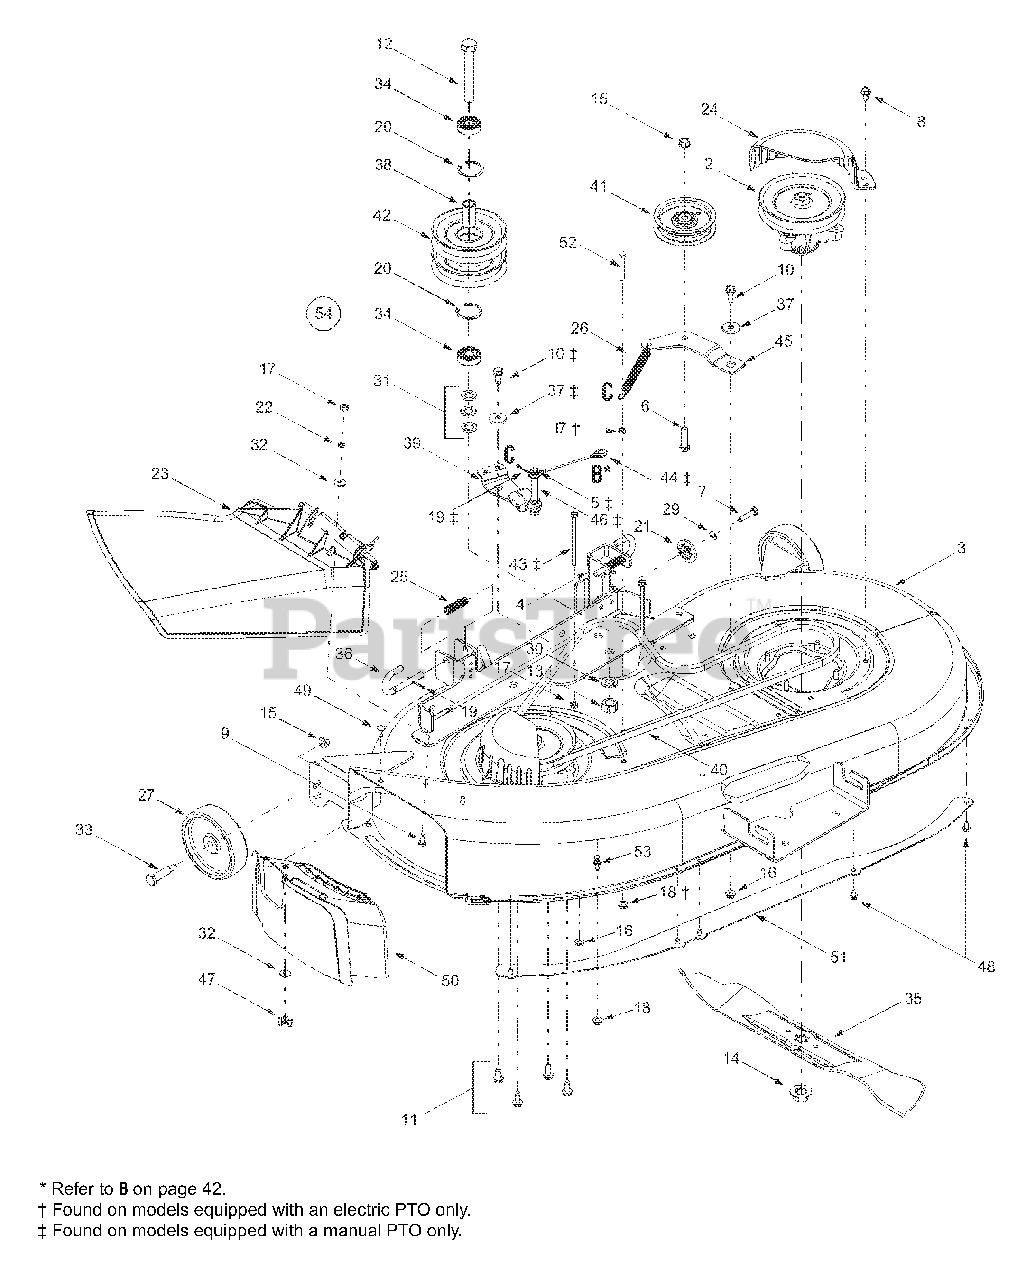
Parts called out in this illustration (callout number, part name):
2	Spindle Assembly, 5.75 Dia.
5	Flat Washer, .385 x .62 x .063
6	Hex Cap Screw, 1/4-20 x 1.5
7	Hex Cap Screw, 5/16-18 x 1.25
8	Self-tapping Screw, 5/16-18 x .75
9	Hex Cap Screw, 1/4-20 x .62
10	Hex Head Washer Screw, 5/16-18 x .875
11	Self-tapping Screw, 5/16-18 x .88
12	Hex Cap Screw, 5/8-18 x .875
13	Hex Nut, 5/8-18
14	Hex Flange Nut, 5/8-18
15	Flange Lock Nut, 3/8-16
16	Flange Lock Nut, 5/16-18
17	Hex Nut, 1/4-20
18	Hex Flange Lock Nut, 1/4-20
19	Cotter Pin, 1/8 x 1.25
20	Internal Snap Ring
21	Deck Adjustment Gear
22	Push Nut. .25 x .5
23	Side Discharge Chute Assembly
24	Belt Cover
25	Compression Spring, .406 x .531 x 1.75
26	Extension Spring, .50 x 4.74
27	Deck Wheel, 5 x 1.38
29	Lock Washer, 5/16
30	Lock Washer, 5/8
31	Flat Washer, .64 x 1.0 x .12
32	Bell Washer, .265 x .75 x .062
33	Shoulder Screw, .498 x 1.53
34	Bearing, .625 x 1.574 x .470
35	Three-in-one Blade, Star Center, 21.23"
36	Deck Release Pin
37	Shoulder Spacer, .625 x .324
38	Spacer, .635 x .88 x 1.72
39	Deck Brake Assembly
40	Deck Belt
41	Idler Pulley, 3.5
42	Double Pulley, 5.0
43	Self-tapping Screw, 1/4-20 x 4.0
44	Brake Cable, 5.05
46	Pin, 3/8-16, 3/8 x 3.27
47	Wing Nut, 1/4-20
48	Self-tapping Screw, 1/4-20 x .5
49	Carriage Screw, , 1/4-20 x .62
50	Mulch Plug
52	Hex Cap Screw, 1/4-20 x 1.75
53	Grass catcher Pin
